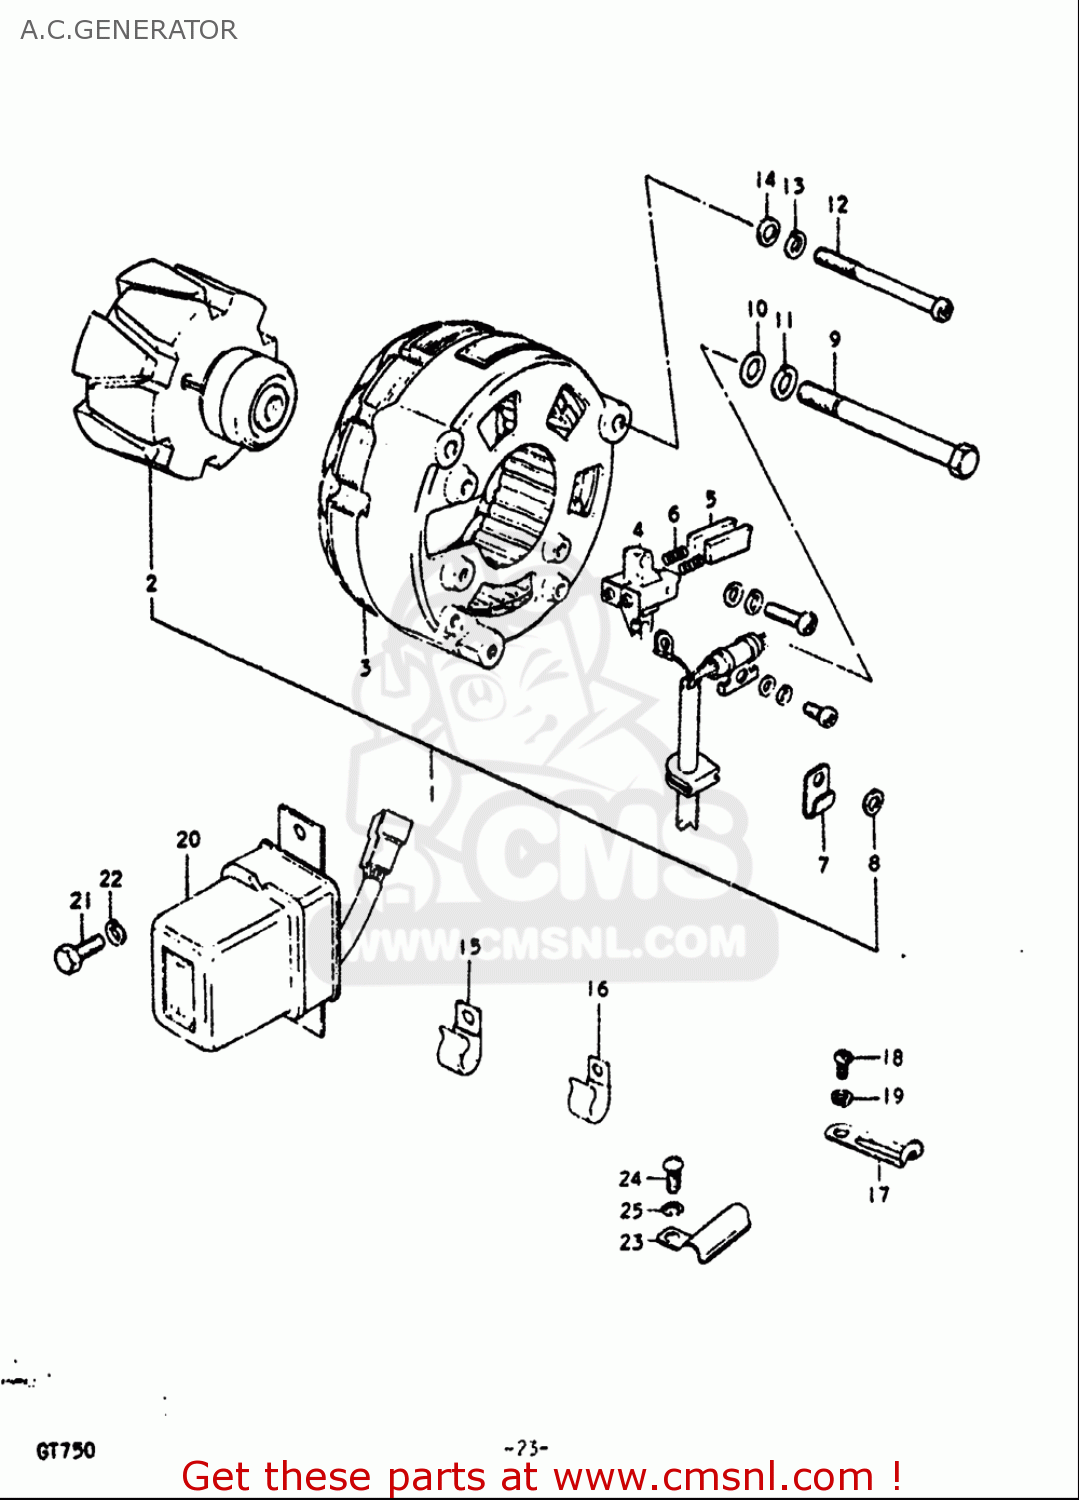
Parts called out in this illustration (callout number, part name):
5	BRUSH
6	SPRING
10	WASHER (8.2X22X3.2)
11	WASHER,LOCK
12	SCREW 5X65 CROS
13	WASHER,LOCK
14	WASHER
15	CLAMP(L:120 T:1.0)
16	CLAMP
17	REGULATOR ASSY,VOLTAGE
18	BOLT
19	WASHER,LOCK
21	SCREW
22	WASHER,LOCK
